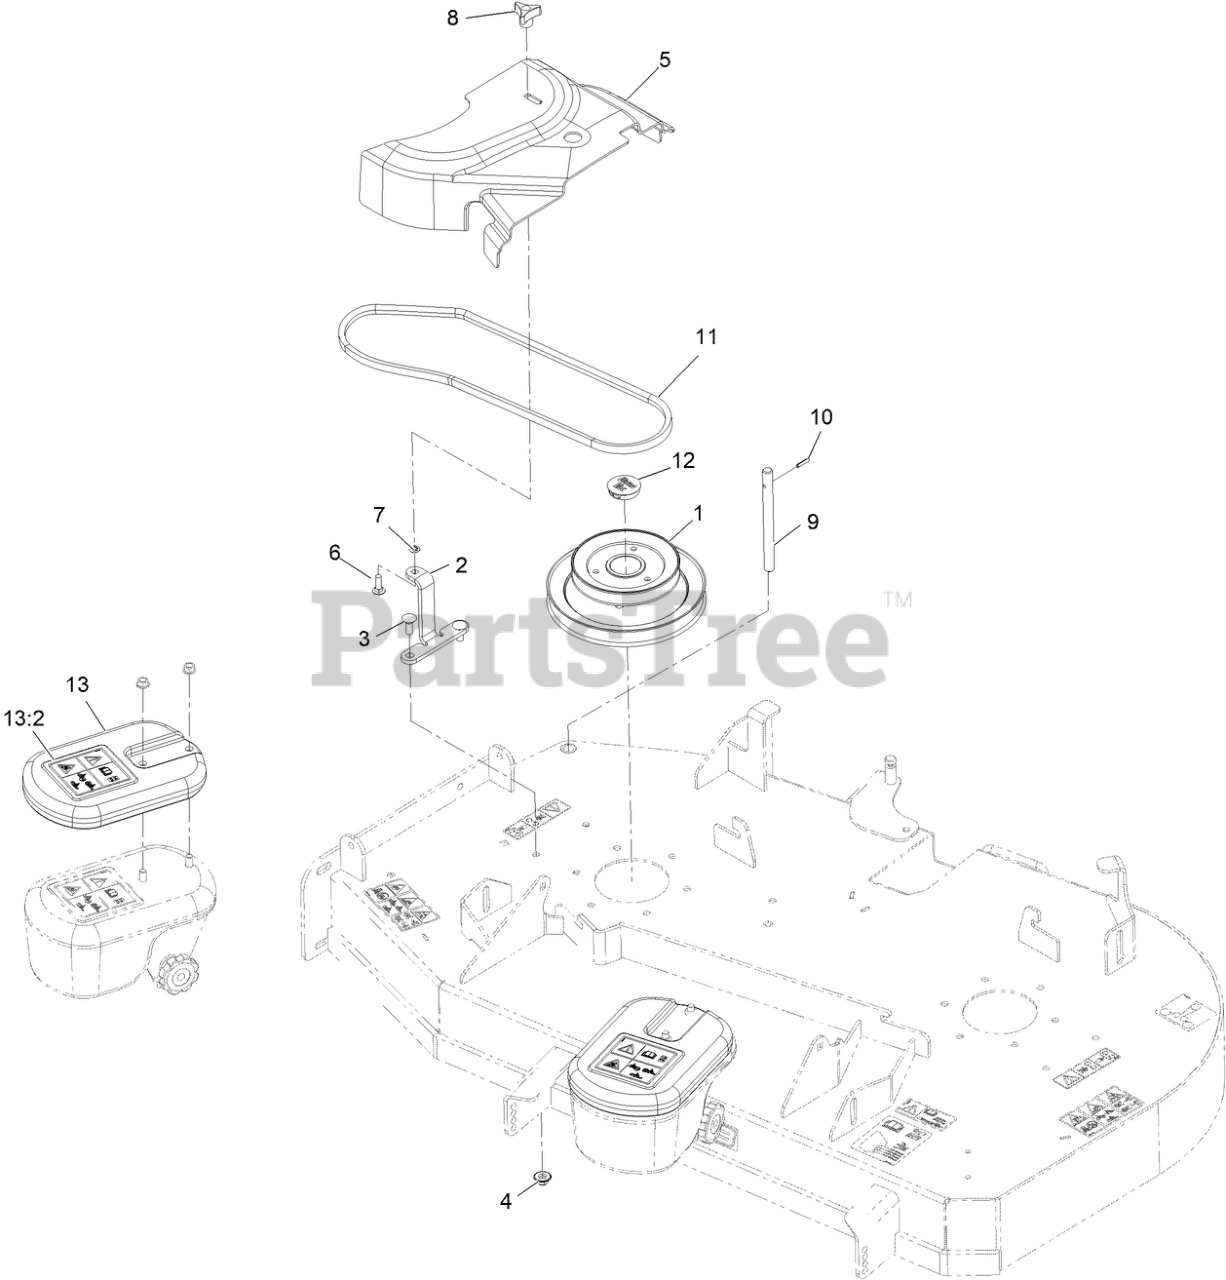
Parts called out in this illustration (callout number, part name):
1	Jackshaft-Uv Drive 482B Splined
2	Bracket-Cover
3	BOLT-CARR
4	Nut-Nyloc 3/8-16 Flg
5	COVER-BELT BLOWER
6	BOLT-CARR
7	RING-RETAINING, BOLT
8	KNOB-3 PRONG
9	SHAFT-CATCHER, GRASS
10	PIN-ROLL
11	BELT-V
12	PLUG, BLACK NYLON 1.75
13:2	DECAL-WARNING, TRACTION
